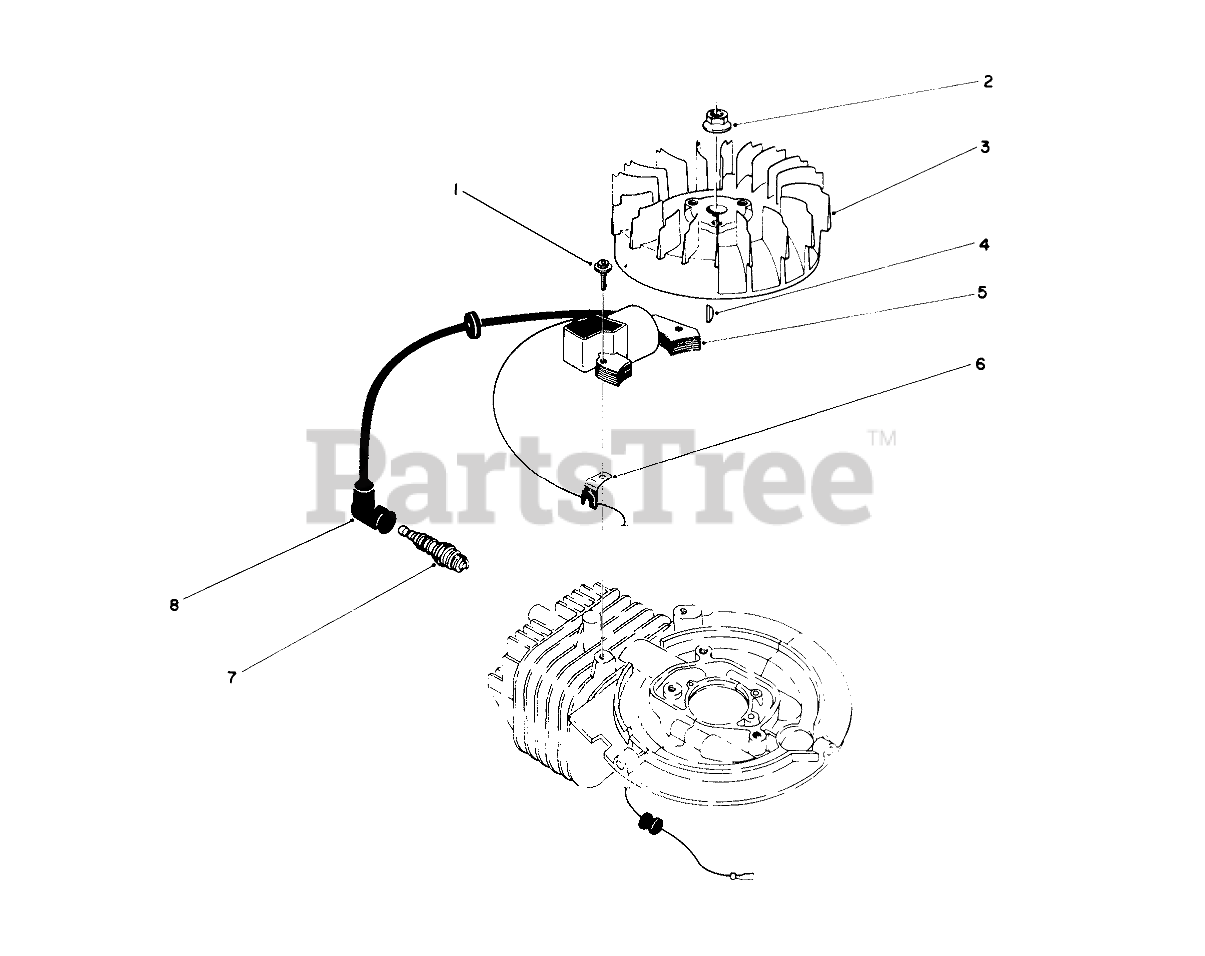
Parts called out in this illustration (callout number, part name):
1	Allenhead
3	FLYWHEEL
4	Key-Flywheel
5	Coil/Ignition Assembly
6	CLAMP
7	Sparkplug
8	CAP-SPARKPLUG
